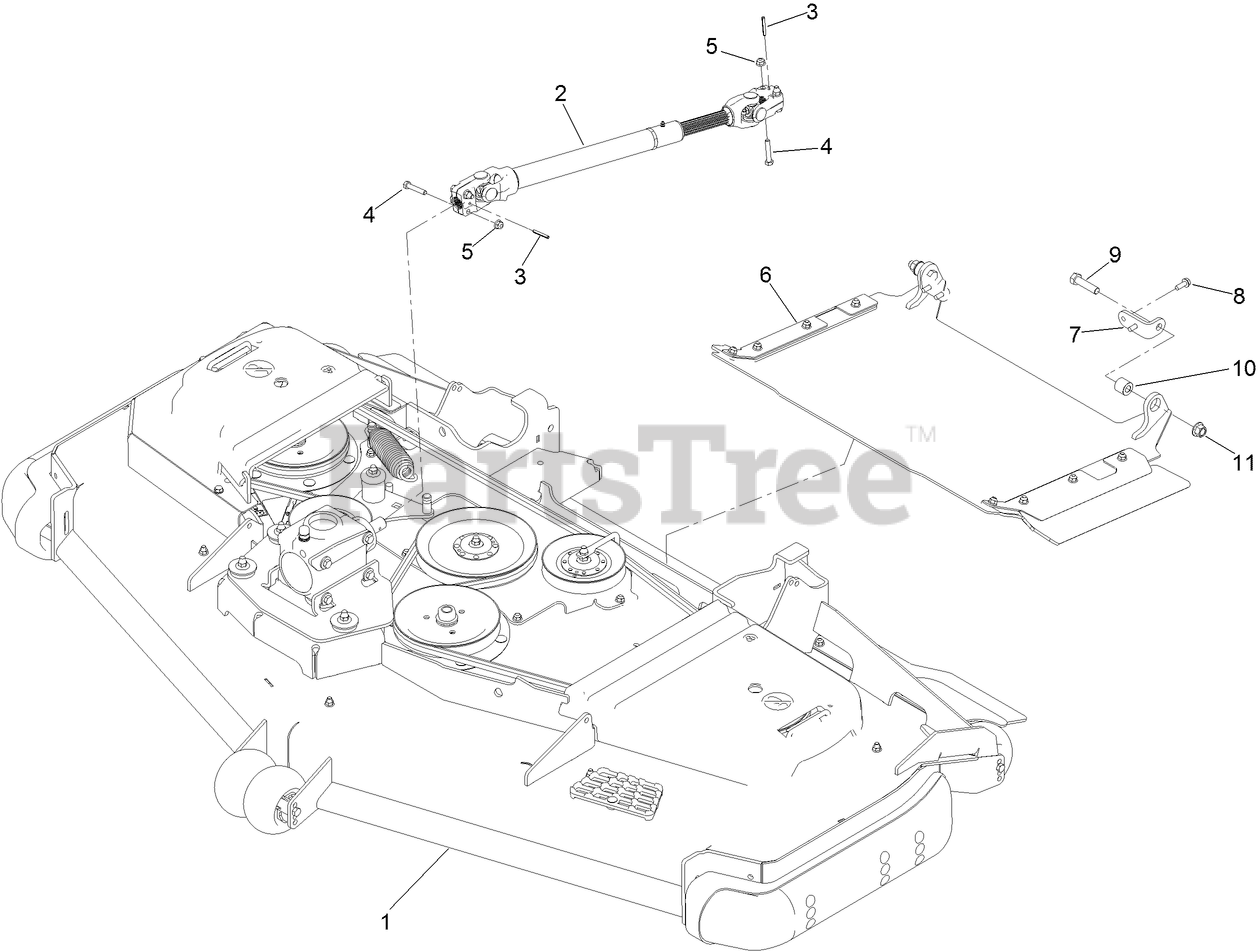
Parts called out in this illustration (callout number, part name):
2	DRIVESHAFT ASM
3	PIN-ROLL
4	SCREW-HH
5	NUT-HF, NI
6	DISCHARGE TUNNEL ASM
7	BRACKET-DISCHARGE
8	SCREW-TAPTITE
9	SCREW-HH
10	BUSHING-SLEEVE
11	NUT-LOCK
